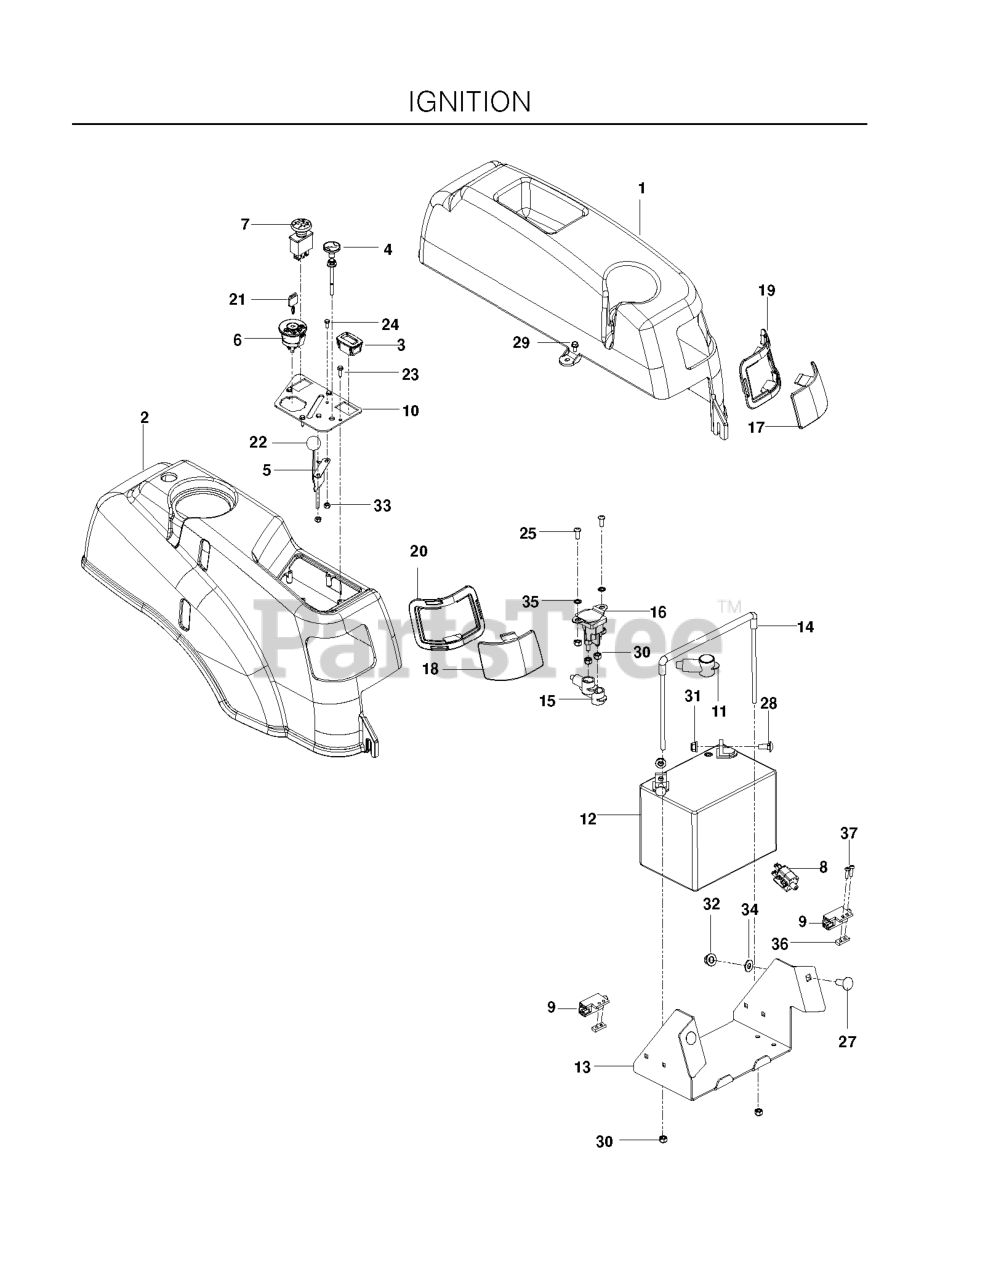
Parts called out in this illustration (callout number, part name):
1	FENDER, LT
2	FENDER, RT, GRAY
3	HOUR METER
4	CHOKE CABLE
5	THROTTLE CABLE
6	RP IGNITION SWITCH
7	RP.SWITCH, BLADE
8	SWITCH, BRAKE 3P
9	SWITCH INTERLOCKT
10	CONSOLE.PLATE.BLACK
12	BATTERY, 12 V 330 AMP
13	BOX, BATTERY, BLACK
14	BATTERY TIE DOWN ASSEMBLY
15	TERMINAL COVER-SM
17	LENS, COLORED LEFT
18	LENS, COLORED RIGHT
19	LEFT HEADLIGHT RIM GREY
20	RT HEADLIGHT RIM GREY
21	KEY
22	KNOB.ROUND.BALL.BLACK
23	HCS #10-24 X 1/2
24	SCR #10-12X3/4 HEX WAS HD ZD
25	SCR 1/4-20 X 5/8 BTN SKT HD ZD
27	RHSNB 3/8C X 1
28	BOLT 5/16C X 3/4" CARRIAGE
29	BOLT 1/4-20 X 1/2 HWST
30	NUT.1/4-20.HEX.NYLOC.ZD
31	5/16-18 NYLOC FLANGE NUT
32	NUT 3/8-16 NYLOC
33	NUT 10-24 NYLOC
35	WASHER 1/4 INT TOOTH
36	TAPPED PLATE
37	SCR #10-24 X .75 SKT HD BLK
